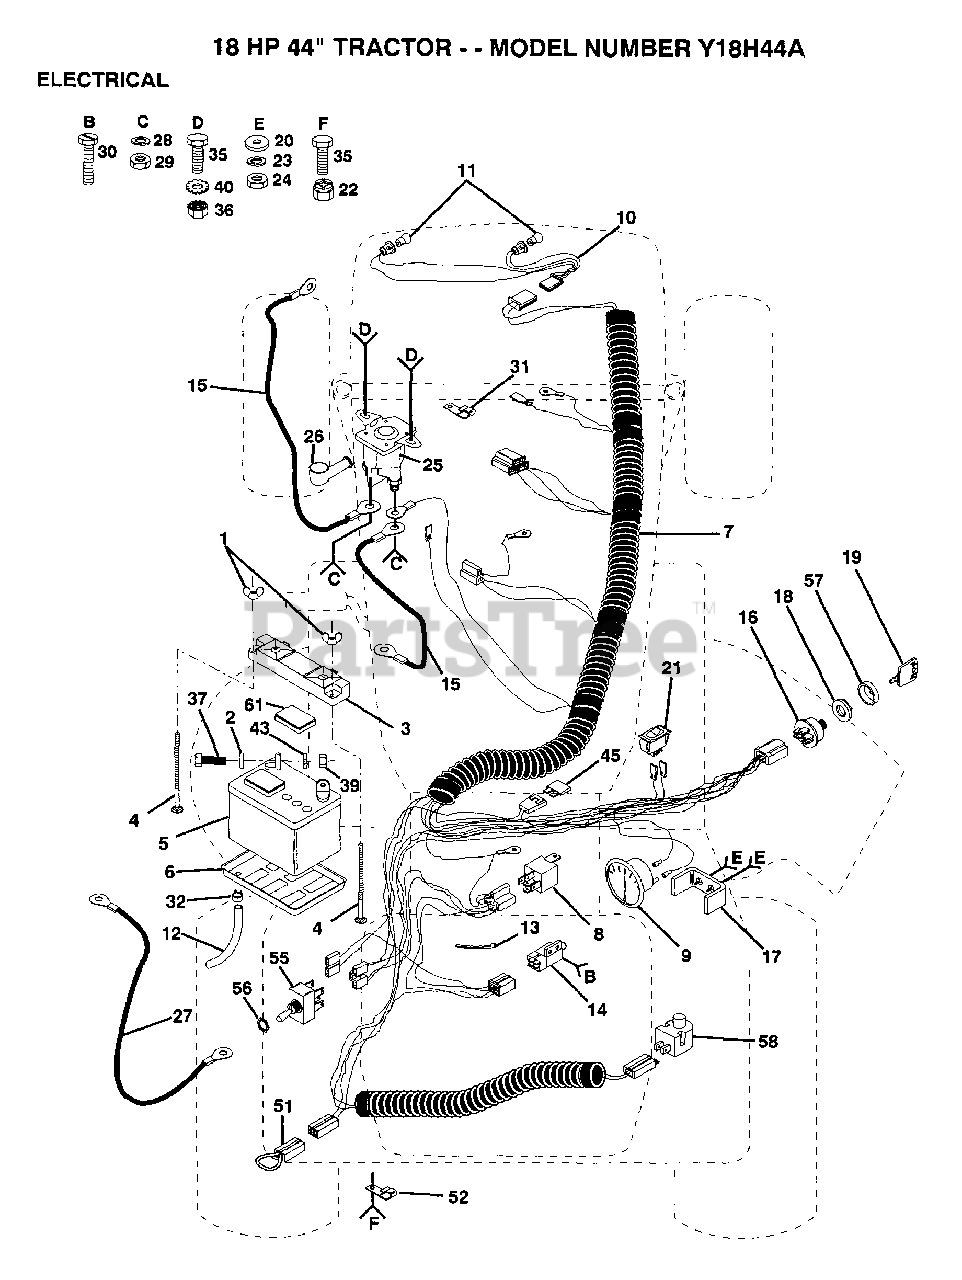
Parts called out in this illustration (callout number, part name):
2	WASHER
4	BOLT
6	"TRAY T, BATTERY"
8	RELAY ASSY T
9	AMMETER T
13	WIRE TIE
14	SWITCH INTERLOCKT
15	CABLE-BATTERY T
18	NUT IGNITION
19	KEY
20	WASHER
21	SWITCH LT
27	CABLE T
29	NUT
30	SCREW
31	CLIP T
32	HOSE CLAMP T
35	BOLT
36	NUT
37	BOLT LT
43	LOCKWASHER
45	FUSE HYT
52	CLIPT
56	HEX NUT T
58	SWITCH SEAT
61	"CAP,BATTERY "
